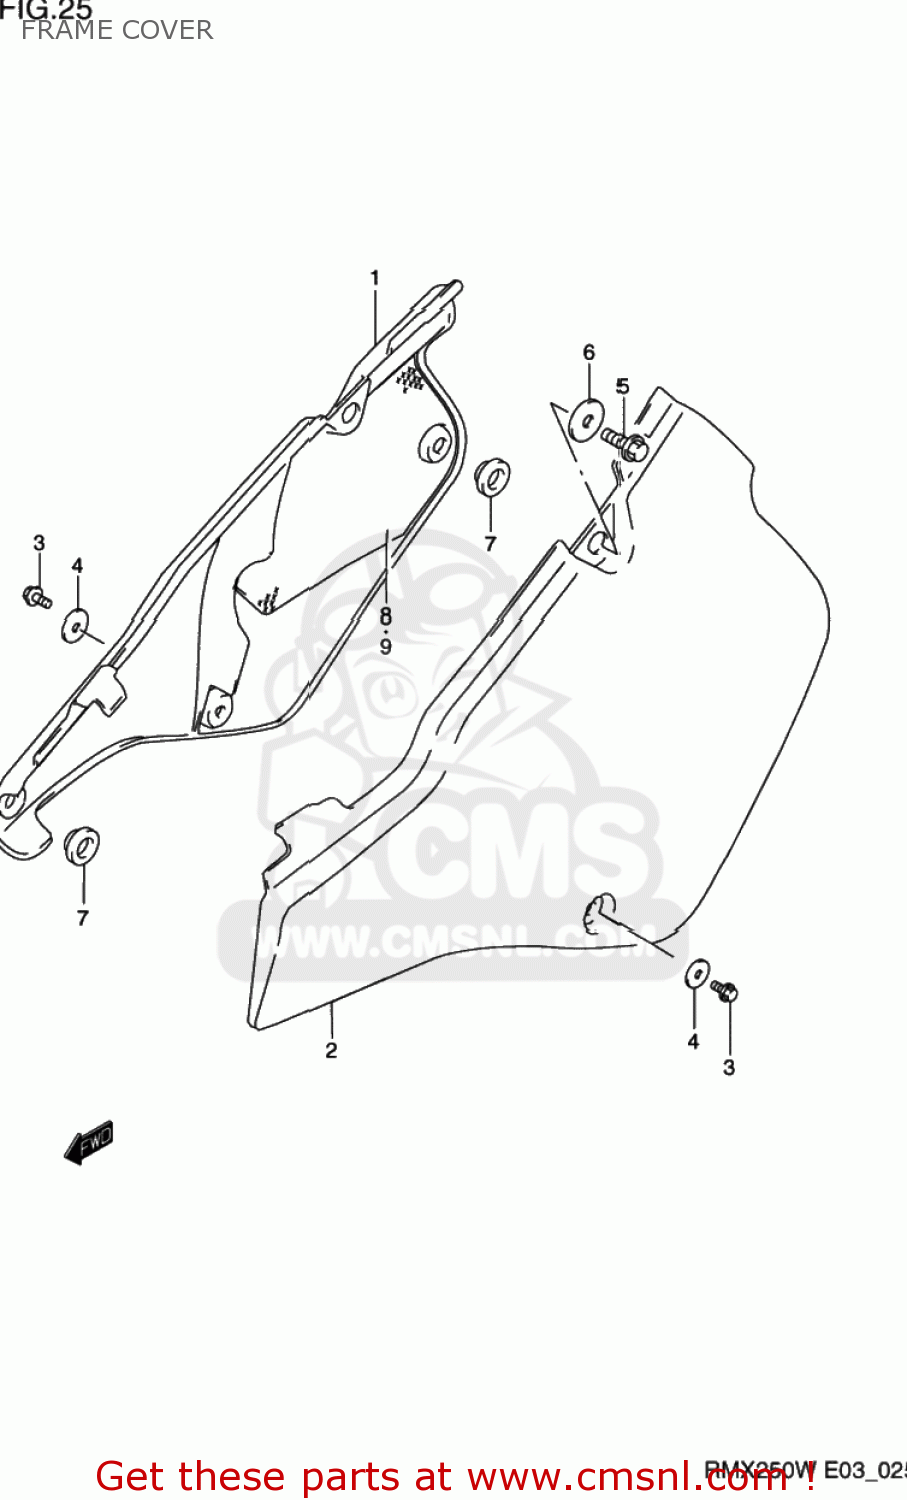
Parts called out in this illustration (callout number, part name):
1	COVER,FRAME,R(WHITE)
2	COVER,FRAME,L(WHITE)
3	BOLT
4	GASKET(6.5X20X1.5) (NAS)
5	BOLT
6	WASHER
7	CUSHION
8	HEATSHIELD,FRAME COVER,R
9	SHIELD,FRAME COVER,RIGHT
